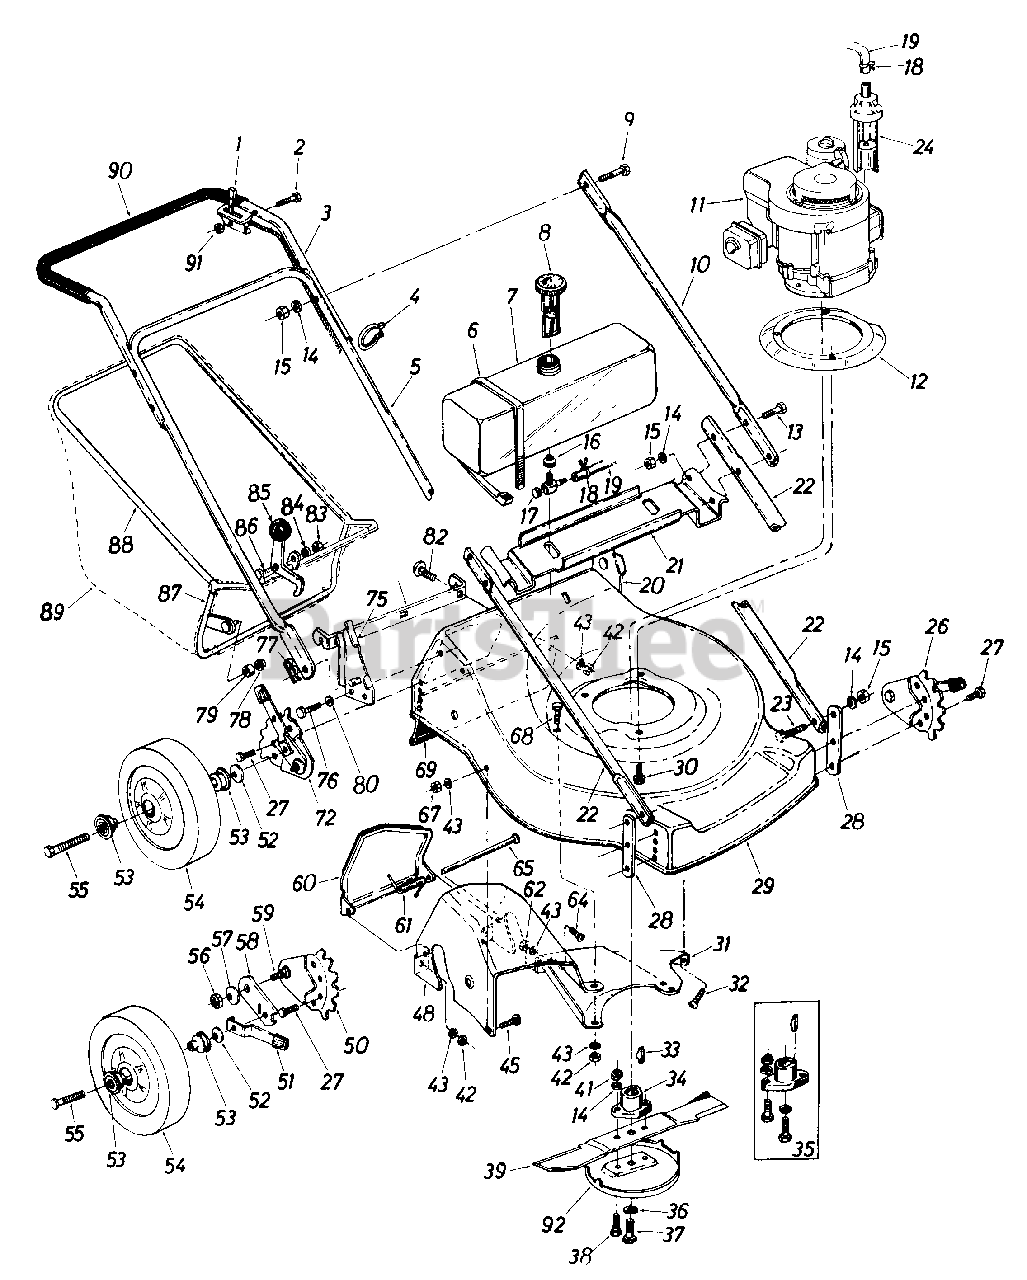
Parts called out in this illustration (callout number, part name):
1	Throttle Control Ass'y. Comp
2	Hex Bolt 1/4-20 x 1.50" Lg.
3	Upper Handle
4	Plastic Cable Tie
5	Lower Handle
6	Fuel Tank Straps
7	Fuel Tank
8	Fuel Gauge
9	Hex Bolt 5/16-18 x 1.75" Lg.
10	Upper Strut
11	Engine
12	Engine Mount Cover Plate
13	Hex Bolt 5/16-18 x 1.50" Lg.
14	L-Wash. 5/16" I.D.
15	Hex Cent. L-Nut 5/16-18 Thd.
16	Bushing (Fuel Tank)
17	Fuel Shut-Off Valve
18	Hose Clamp 3/8" I.D.
19	Fuel Line
20	Handle Mount Brkt. Ass'y.
21	Fuel Tank Mounting Brkt.
22	Lower Strut
23	Hex Bolt 5/16-18 x .75" Lg.
24	Fuel Control Valve
26	Height Adjuster Ass'y. Comp. - L.H.
27	Hex Sems Bolt 3/8-16 x .62" Lg.
28	Strut Mounting Bracket
29	22" Deck Ass'y.
30	Hex Wash. Hd. Self-Tap Scr. 3/8-16 x .88" Lg.
31	Rear Chute Baffle - L.H.
32	Carriage Bolt 1/4-20 x .50" Lg.
33	#6 Hi-Pro Key 5/32 x 5/8" Dia.
34	Blade Adapter Kit
35	Blade Adapter Kit
36	L-Wash. 3/8" I.D. - H.D.
37	Hex Bolt 3/8-24 x 1.50" Lg. (Grade 5)
38	Hex Bolt 5/16-24 x 1.00" Lg. (Grade 5)
39	22" Blade
41	Hex Nut 5/16-24 Thd.
42	Hex Nut 1/4-20 Thd.
43	L-Wash. 1/4" I.D.
45	Carriage Bolt 1/4-20 x .50" Lg.
48	Rear Chute Ass'y.
50	Index Plate
51	Spring Lever Ass'y. w/Knob
52	Bell-Wash. 3/8" I.D.
53	Flanged Ball Bearing
54	Wheel Ass'y. Comp. 8 x 1.75
55	Hex Bolt 3/8-16 x 2.00" Lg.
56	Hex Cent. L-Nut 3/8-16 Thd.
57	Bell-Wash. .50" I.D. x 1.14" O.D.
58	Pivot Bar
59	Shoulder Bolt (3/8-16 Thd.)
60	Chute Door
61	Torsion Spring
62	Hex Sems Nut 1/4-20 Thd.
64	Carriage Bolt 1/4-20 x .50" Lg.
65	Hinge Pin .250" Dia. x 7.25" Lg.
67	Hex Sems Nut 1/4-20 Thd.
68	Hex Bolt 1/4-20 x .62" Lg.
69	Rear Flap Ass'y.
72	Height Adjuster Ass'y. Comp. - R.H.
75	Handle Mount Brkt. Ass'y. - R.H.
76	Hex Wash. Hd. Self-Tap Scr. 1/4-20 x .62" Lg.
77	Hairpin Cotter 5/16" Dia.
78	Push Cap 3/8" Rod
79	Plastic Roller
80	Fl-Wash. .281" I.D. x .50" O.D. x .063
82	Carriage Bolt 1/4-20 x .75" Lg.
83	Hex Nut 5/16-18 Thd.
84	L-Wash. 5/16" I.D.
85	Cam Lever - Grip Ass'y.
86	Shld. Bolt .427" Dia. x .180" Lg.
87	Grass Catcher Lower Frame Ass'y.
88	Grass Catcher Upper Frame
89	Grass Bag
91	Hex Cent. L-Nut 1/4-20 Thd.
92	Scalp Plate
